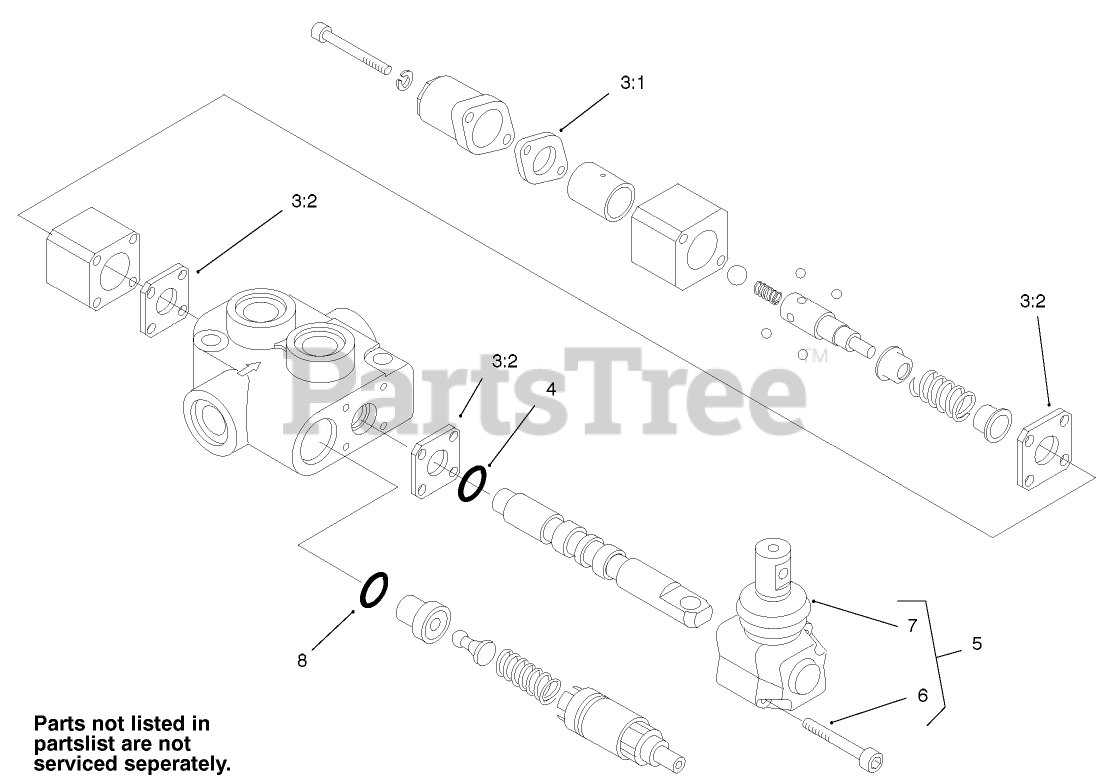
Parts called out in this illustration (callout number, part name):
3	SEAL KIT
3:1	GASKET
3:2	GASKET
